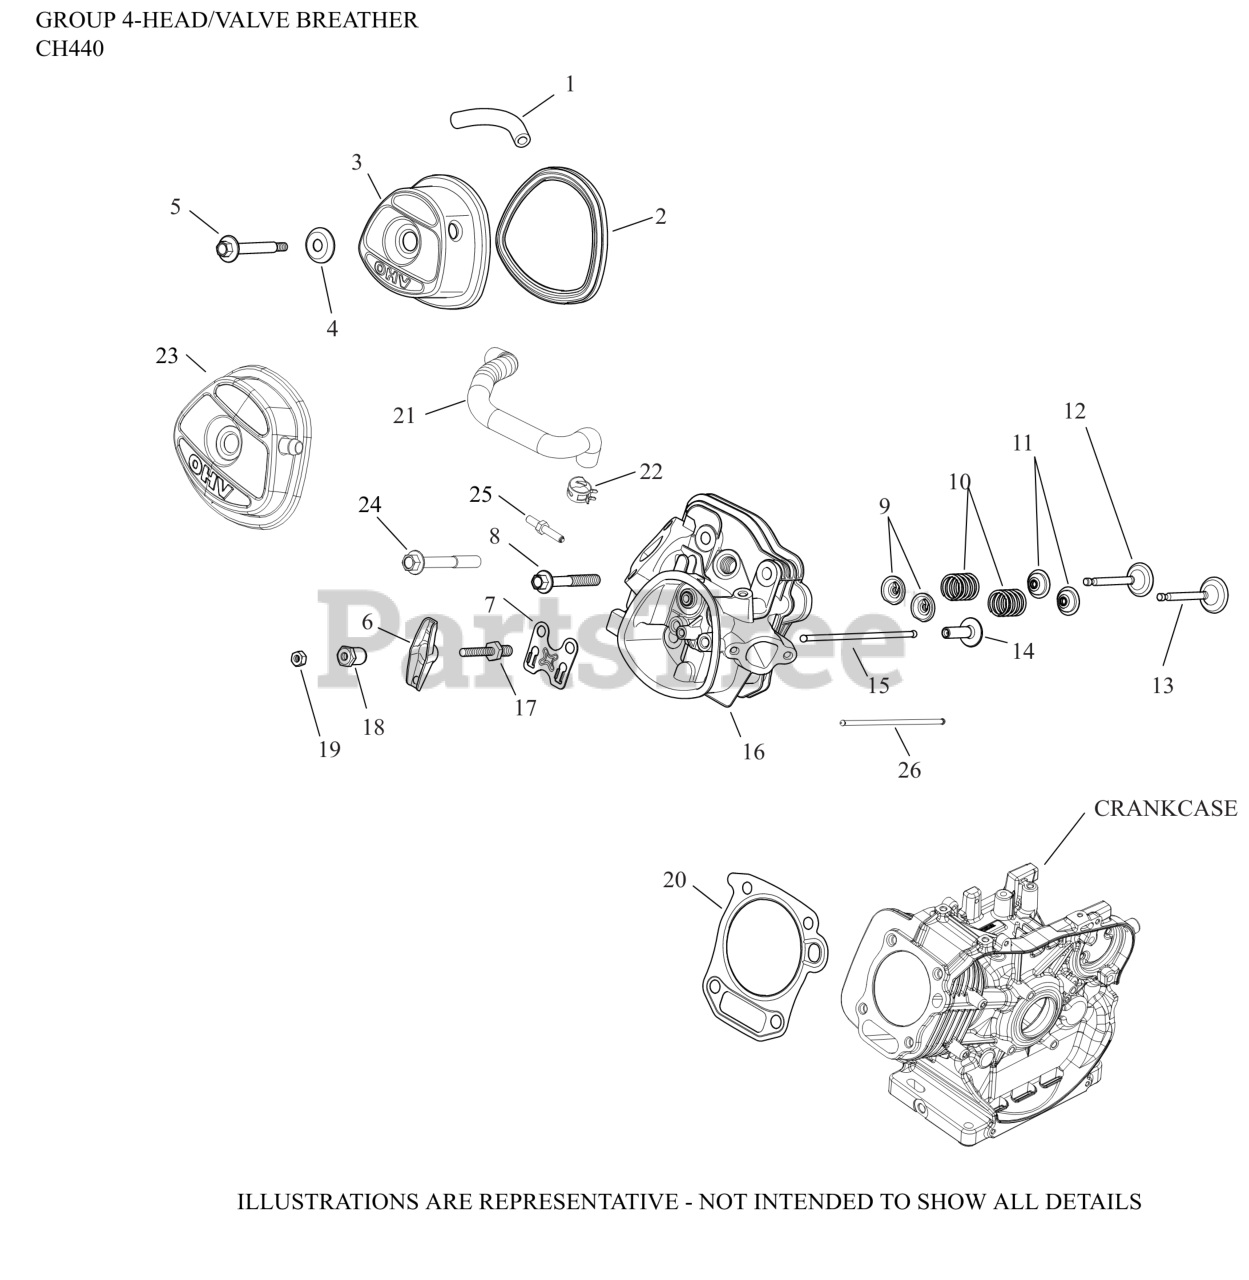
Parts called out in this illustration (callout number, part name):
1	TUBE, BREATHER
2	GASKET, VALVE COVER
3	KIT, VALVE COVER ASSEMBLY
5	SCREW, VALVE COVER SEAL ASSY
6	ARM, ROCKER
7	PLATE, PUSHROD GUIDE
8	SCREW, HEX FLANGE CYLINDER HEAD
9	RETAINER, VALVE SPRING
10	SPRING, VALVE
11	SEAL, VALVE STEM
12	VALVE, EXHAUST
13	VALVE, INTAKE
14	LIFTER, VALVE
15	ROD, PUSH
16	KIT, HEAD ASSY
17	STUD, ROCKER ARM-USE 14 072 22-S
18	PIVOT, ROCKER ARM
19	NUT, HEX JAM
20	KIT, HEAD GASKET-(#1784173S)
